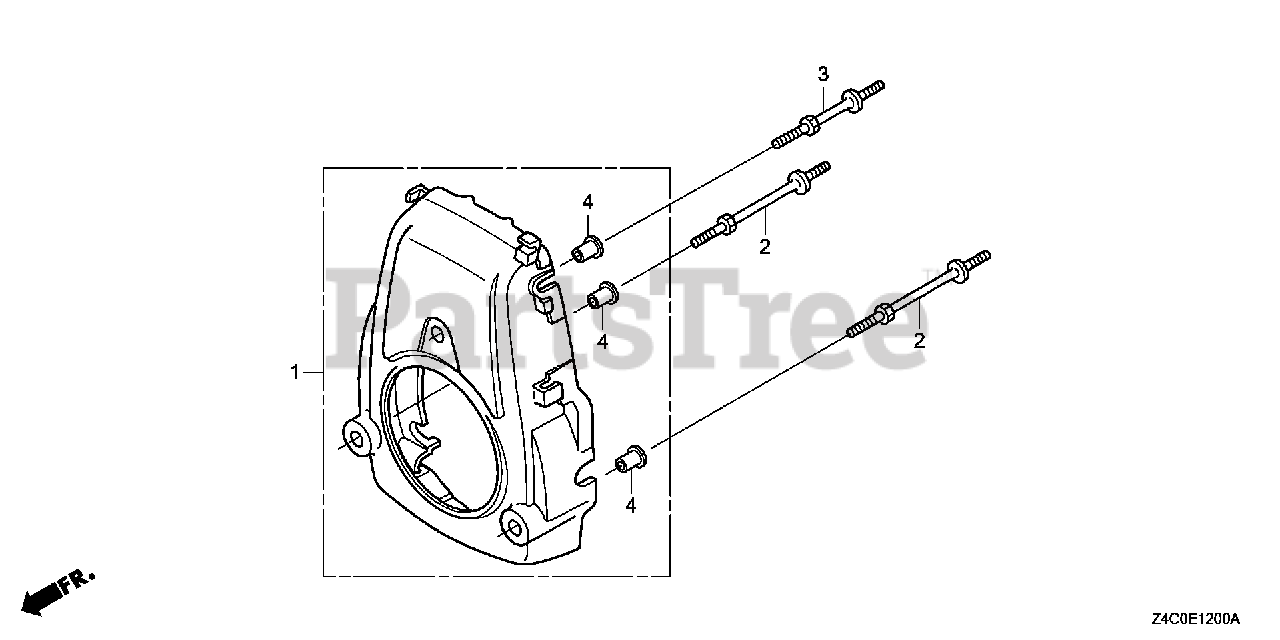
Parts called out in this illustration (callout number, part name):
1	COVER, FAN *R280* (POWER RED)
2	BOLT A, STUD
3	BOLT B, STUD
4	COLLAR, FAN COVER
